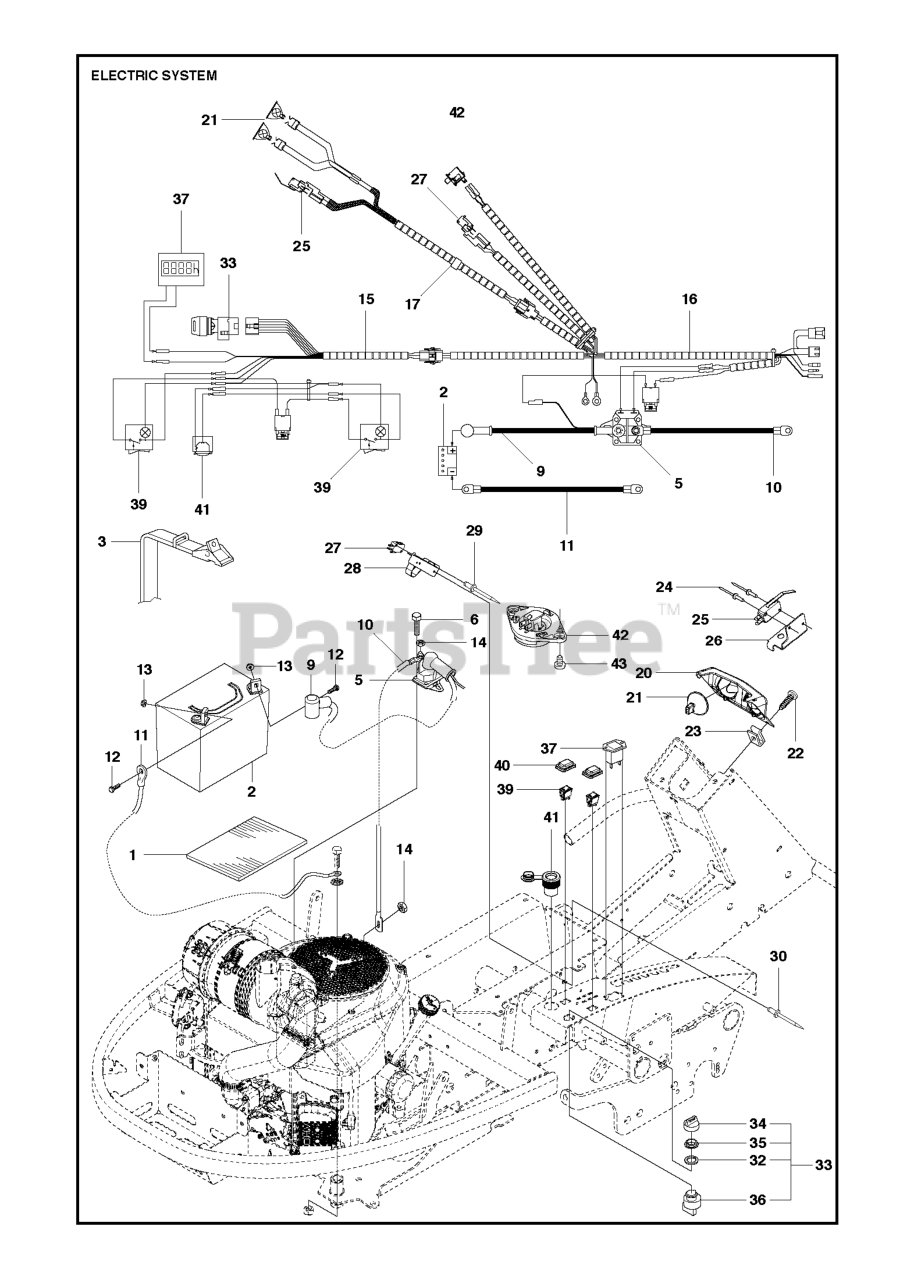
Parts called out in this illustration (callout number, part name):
12	SCREW EHHM
25	MICRO SWITCH
43	SCREW
